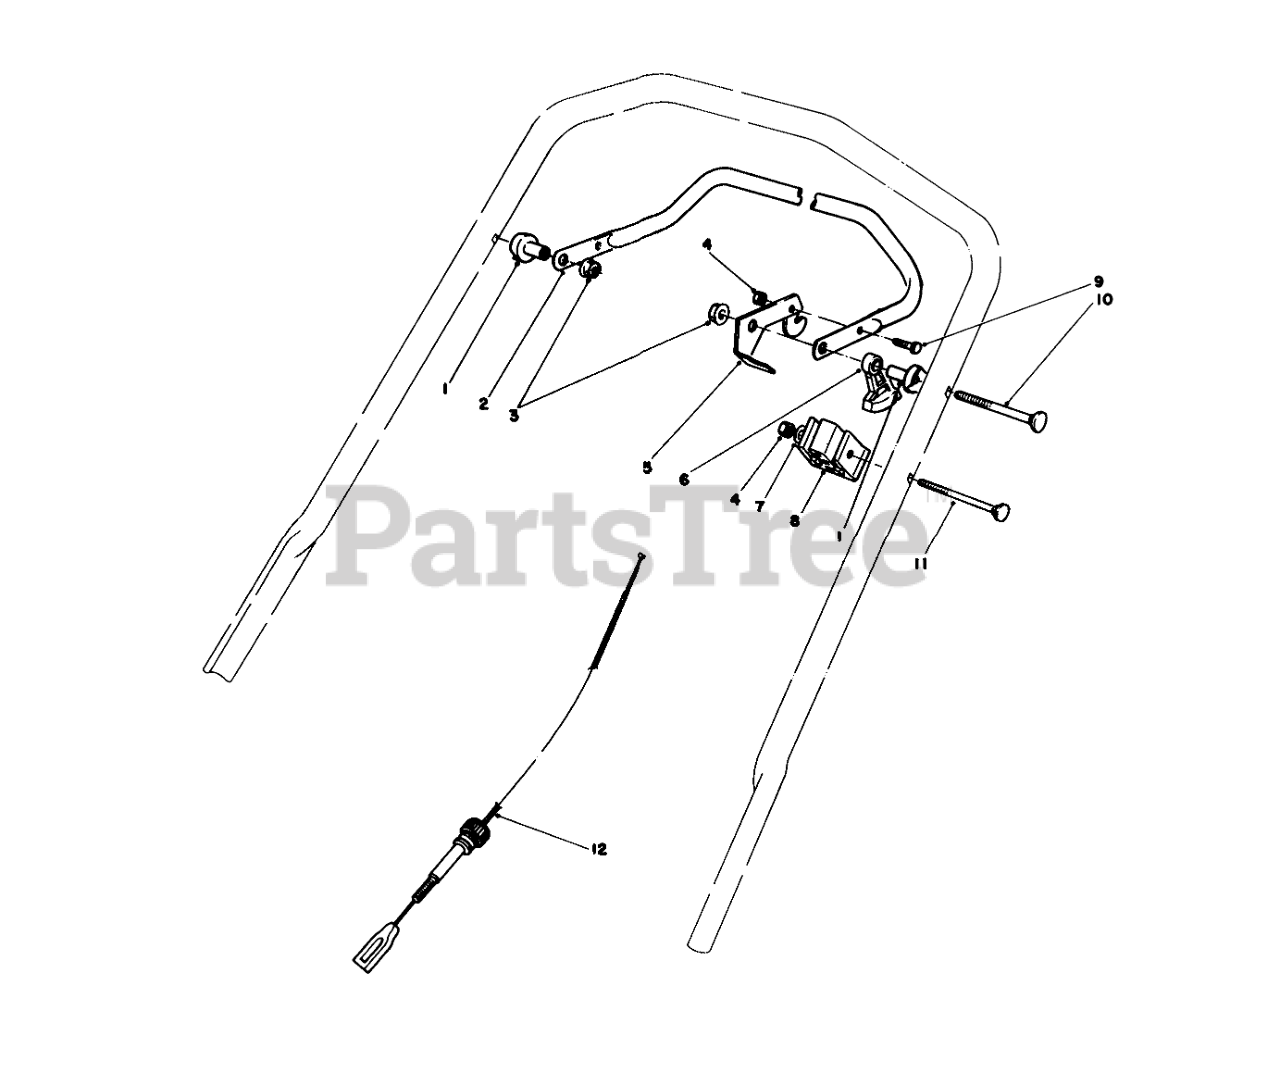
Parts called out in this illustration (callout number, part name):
1	SPACER-SUPPORT
2	Bar-Control
3	NUT-LOCK, NI
4	NUT-LOCK, NI
5	CONTROL LEVER
6	LEVER-TRACTION
7	WASHER-FLAT
8	SUPPORT-CABLE
9	SCREW-HH
10	5/16-18 X 2 HNDLE SCREW
11	HANDLE SCREW
12	CABLE-TRACTION
